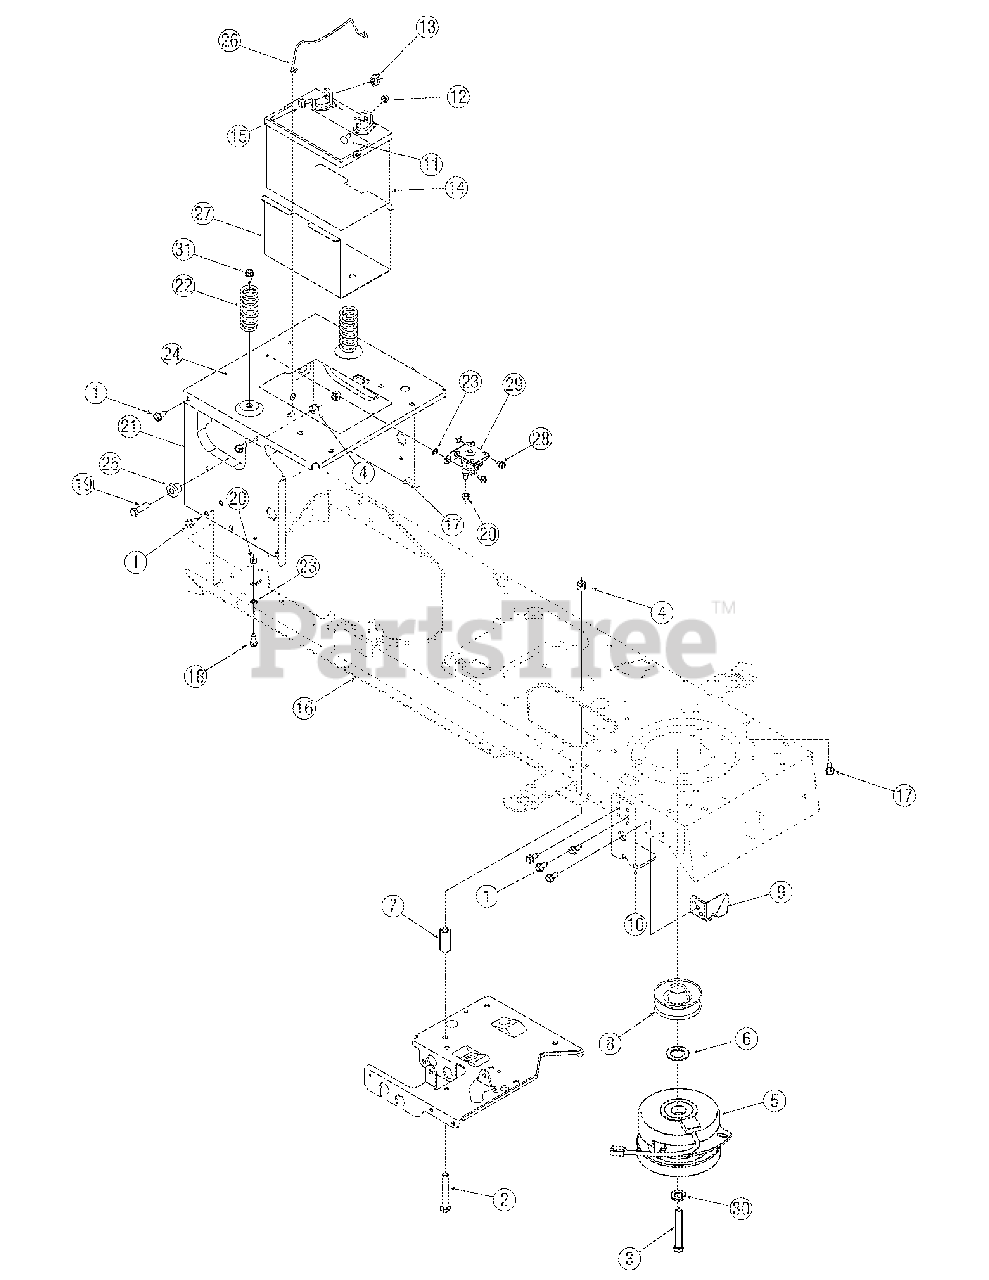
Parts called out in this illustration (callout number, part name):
1	Screw, 5/16-12, 0.75
2	Screw, 3/8-16, 2.50, Gr5
3	Screw, 7/16-20, 3.50, Gr5
4	Nut, Flange Lock, 3/8-16, GrF
5	PTO Clutch, Electric
6	Washer, Flat, 1.031 x 1.620 x.095
7	Spacer,.385 ID x.635 OD x 1.54
8	Pulley, Engine, Electric PTO
11	Screw, Carriage, 1/4-20,.75, Gr5
12	Nut, Sems, 1/4-20
13	Nut, Wing, 1/4-20
14	Battery, 235 CCA
15	Screw, Shldr,.250 x.150, 1/4-20
18	Screw, 1/4-20, 0.750
19	Screw, 3/8-16, 1.25, Gr5
20	Nut, Flange Lock, 1/4-20, GrF
23	Washer, Lock, 1/4, External
26	Hold Rod, Battery
29	Solenoid, 12V, 100 Amp
30	Lock Washer, 7/16
31	Screw, 5/16-18 x .750
